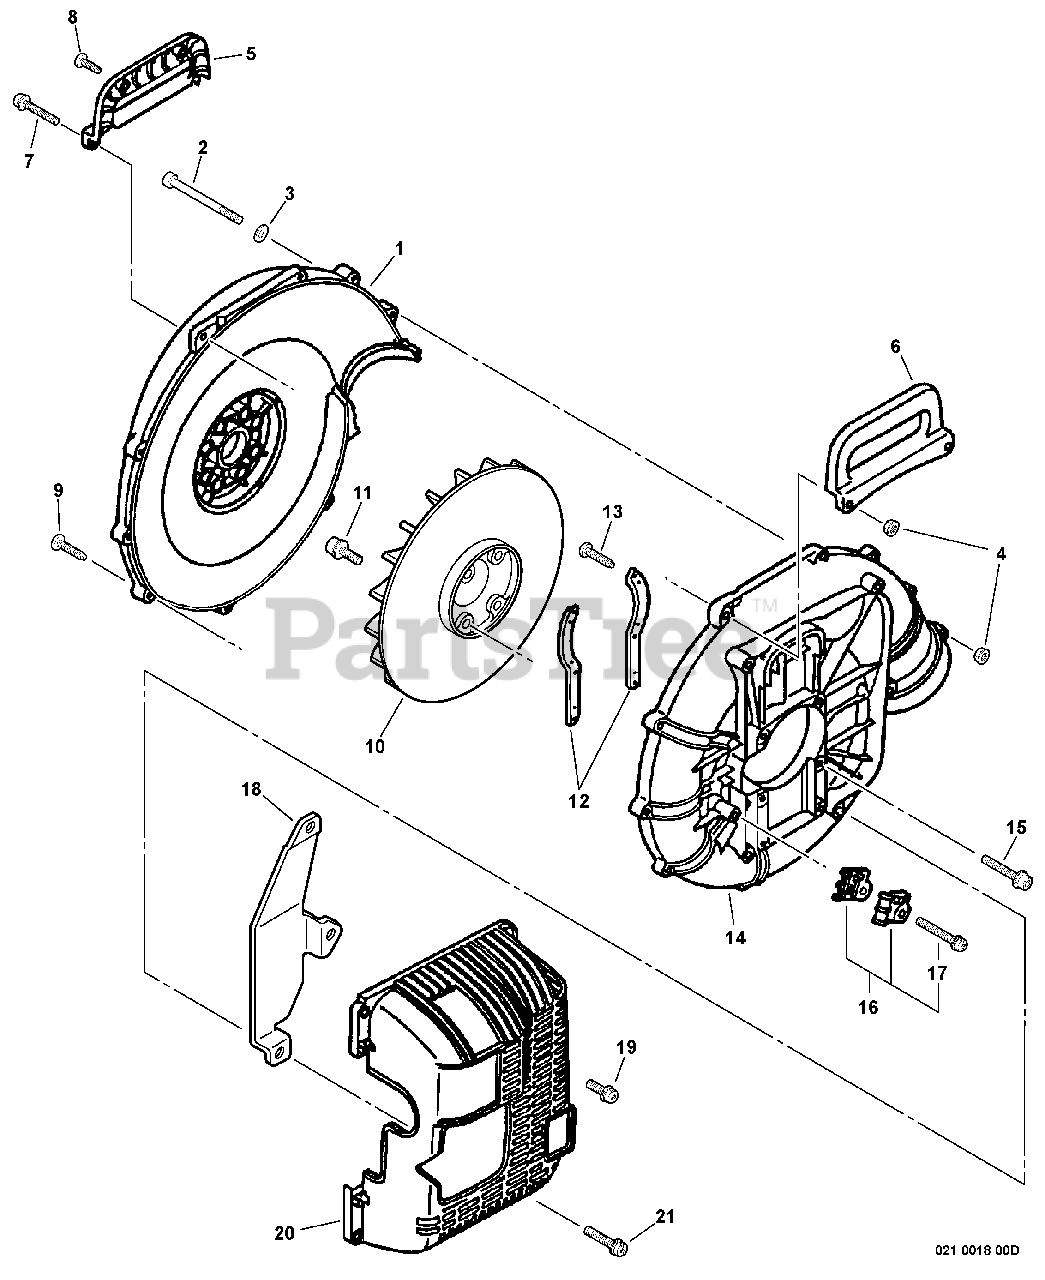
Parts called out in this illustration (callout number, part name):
1	COVER, FAN - INNER
2	BOLT 5×60
3	WASHER 5.3×10×1
4	NUT, FLANGE M5
5	HANDLE
7	SCREW 5×45
8	SCREW 5×16
9	SCREW 5×30
11	BOLT 5×20
12	BRACKET, ENGINE
13	SCREW TAPPING 3×12
14	COVER, FAN - OUTER
15	SCREW 5×32
16	CABLE HOLDER KIT
17	SCREW 5×25
18	INSULATOR
19	SCREW 5×10
20	COVER, ENGINE
21	BOLT 5×18
